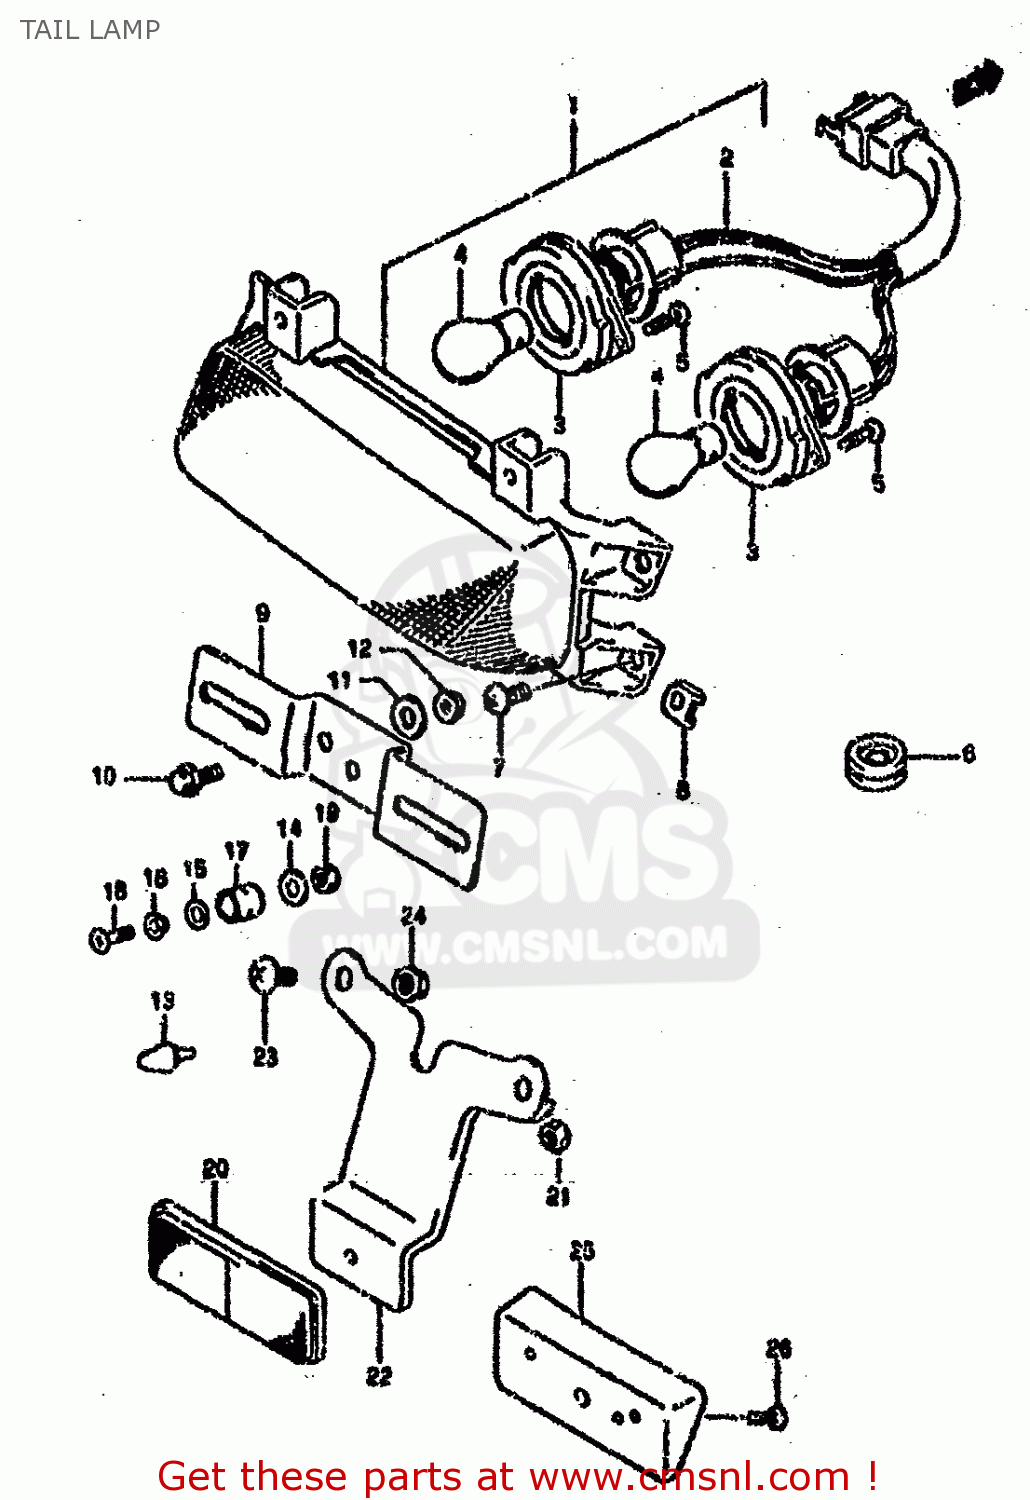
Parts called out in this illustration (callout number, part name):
1	LAMP ASSY, REAR COMBINATION
2	SOCKET & CORD ASSY
3	CUSHION
4	BULB(12V21/5W)
5	SCREW
6	GROMMET
7	SCREW 5X12
8	NUT
9	BRACKET,LICENSE PLATE
10	BOLT
11	WASHER(6.5X20X1.6)
12	NUT
13	CUSHION
14	WASHER
15	WASHER(6.5X16X1.2)
16	WASHER
17	CUSHION, PLATE
18	SCREW
19	NUT
20	REFLECTOR ASSEMBLY,REAR
21	NUT
22	BRACKET,REAR,REAR
23	SCREW 6X12
24	NUT
25	SPACER,RR RR
26	SCREW
